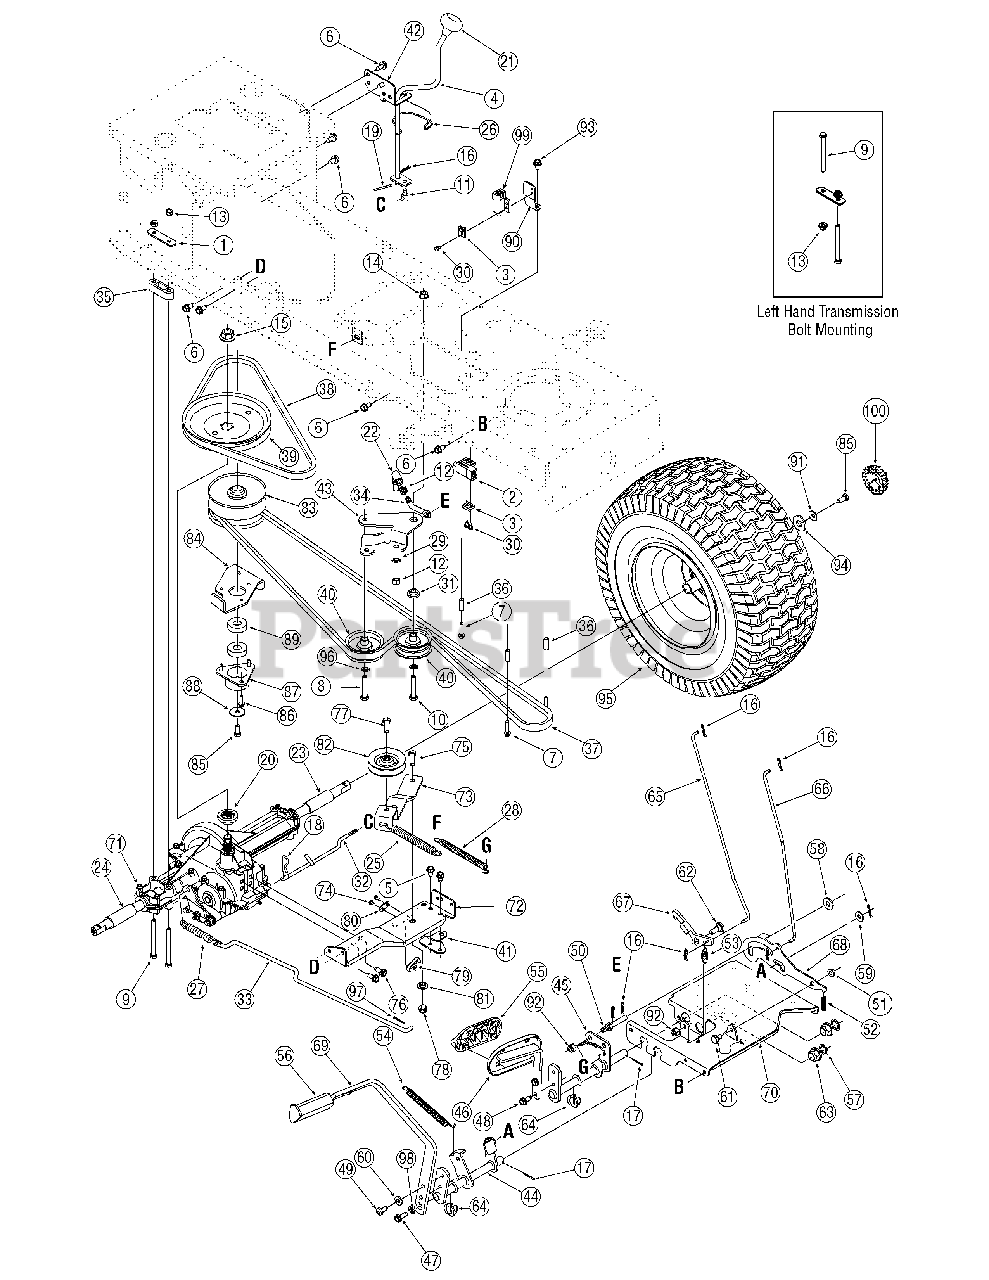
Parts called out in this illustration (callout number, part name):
2	Switch, Interlock
3	Plate, Switch
4	Lever Assembly, Shift
5	Screw, 5/16-18, 0.500
6	Screw, 5/16-12, 0.750
7	Screw, 1/4-20, 1.250
8	Screw, Sems, 3/8-16, 1.500
9	Screw, 5/16-18, 3.50, Gr5
10	Screw, 3/8-16, 2.00, Gr5
11	Adjustment Ferrule 1/4-20 x 1
12	Nut, Hex, 3/8-24, Gr5
13	Nut, Flange Lock, 5/16-18, GrF
14	Nut, Flange Lock, 3/8-16, GrF
15	Nut, Flange, 9/16-18, Gr2
16	Pin, Cotter,.072 Dia. x 1.13
17	Pin, Cotter, 3/32, 1.0
18	Cotter Pin, Internal,.125 Dia.
19	Pin, Cotter, 1/8 x 1.25
20	Pulley Hub, 5/8 Spline
21	Knob, Shift
22	Ball Joint
23	Sleeve,.758 x.821 x 3.3125
24	Sleeve,.758 x.821 x 2.4375
25	Spring, Extension,.62 Dia x 6.12
26	Spring Clip, Shifter
27	Spring, Extension,.59 OD x 4.00
28	Spring, Extension,.50 Dia x 6.37
29	Washer, Lock, 3/8
30	Screw, #10-16,.50
31	Spacer, Shoulder, 1.00 x.38 x.38
32	Rod, Shift
33	Rod, Brake
34	Idler Rod, Adjustable, 3/8
35	Spacer,.68
36	Spacer,.260 x.372 x 1.030
37	Belt, V-Type
38	Belt, V-Type
39	Pulley, V-Type, 7.25 Dia.
40	Idler Pulley, Flat 2.75 OD
41	Bracket, Shift
42	Bracket, Shift, F-N-R
47	Screw, 5/16-18, 0.875
48	Screw,5/16-18, 0.750
49	Screw, 5/16-18, 0.750
50	Pin, 3/8-16 x 2.68
51	Nut, Flange Lock, 5/16-18,
52	Spring, Compression.,.405 x 1.17
53	Spring, Extension,.50 OD x 1.41
54	Spring, Extension,.50 OD x 6.37
56	Pad, Brake
57	Washer, Flat,.64 x 1.24 x.06, HT
58	Washer, Flat,.385 x.870 x.092
59	Washer, Flat,.406 x.875 x.059
60	Washer, Flat,.344 x.750 x.120
61	Screw, Shoulder.437 Dia x.162
62	Screw, Shoulder,.50 x.27 Lg
63	Bearing, Hex Flange
64	Split Bearing, Hex Flange
65	Rod, Brake Lock
66	Rod, Cruise Control
67	Latch, Cruise Control
68	Bracket, Lockout
71	Transmission, Single Speed
72	Bracket Assembly, Torque
73	Bracket, Idler
74	Screw, #8-18 x.50
75	Screw, 3/8-16, 1.00
76	Screw, 5/16-18,.625
77	Screw, 3/8-16, 1.250
78	Nut, Lock, 3/8-16, Nylon
79	Switch Spring, Short
80	Plate, Insulator
81	Spacer, Shoulder
82	Pulley, V-Type, 3.06
83	Pulley Ass’y, Variable Speed
84	Bracket, Pulley
85	Screw, 5/16-24,.750
86	Screw, 1/4-20,.625
87	Cup, Bearing
88	Washer, Flat
89	Ball Bearing
92	Nut, Flange Lock, 3/8-16, GrF
93	Screw, 1/4-20 x.500
94	Flat Washer,.350 x 1.59 x.062
95	Rim Only w/ Valve Stem
96	Flat Washer, .407 x .812 x .135
97	Pin, Cotter, 3/32 x .750
98	Lock Washer, 5/16
99	Switch
100	Hub Cap
